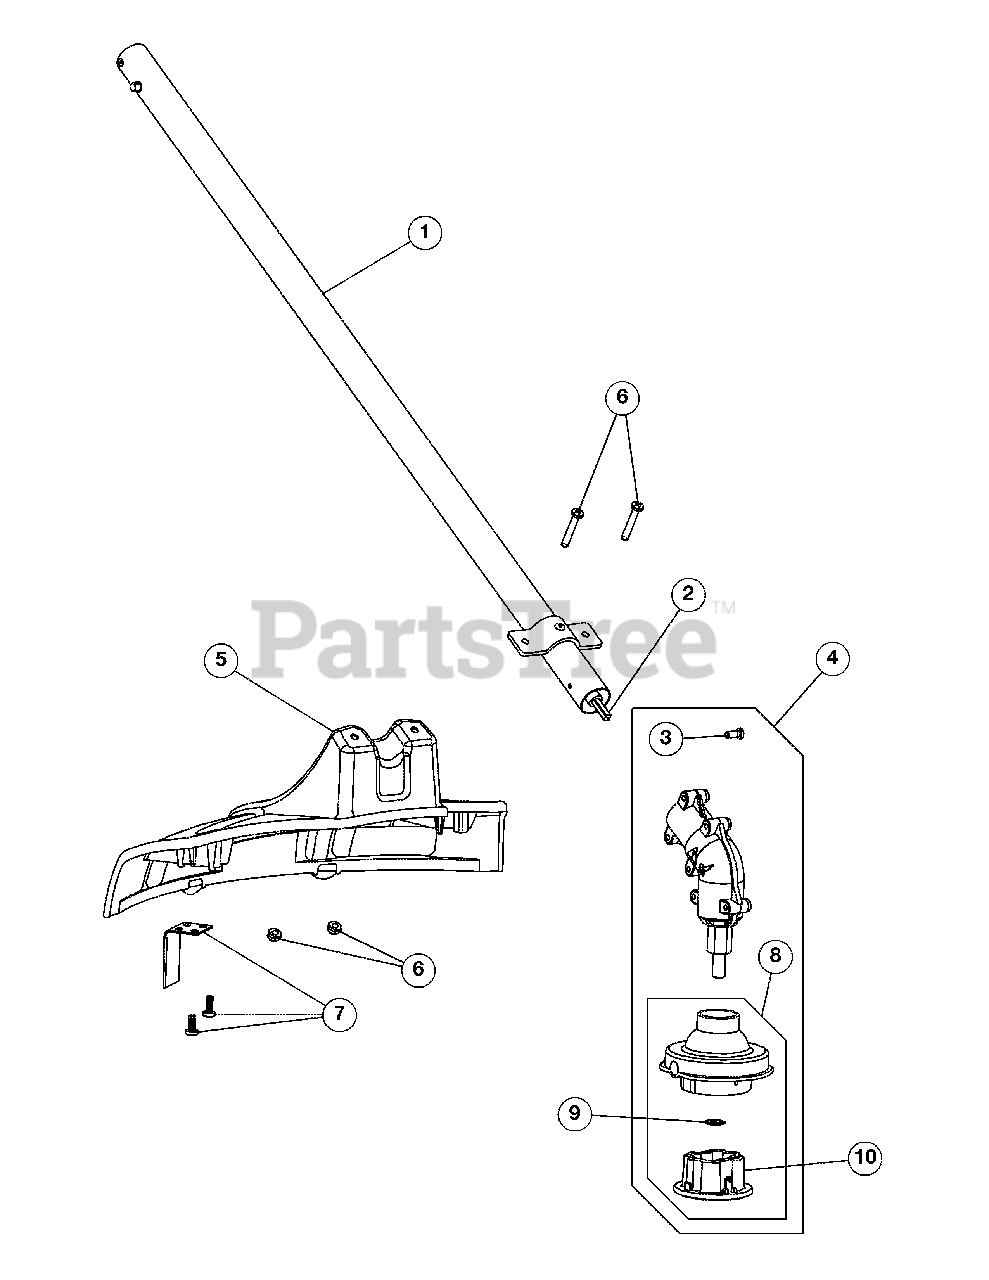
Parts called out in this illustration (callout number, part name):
1	Lower Drive Shaft Housing Assembly
2	Lower Flexible Drive Shaft
3	Anti-Rotation Screw
4	Gear Box Assembly (Incl. 3 & 8)
5	Shield Assembly (Incl. 6 & 7)
6	Shield Mounting Screws
7	Blade Assembly
8	Cutting Head Assembly (Incl. 9 & 10)
9	Retainer
10	Cutting Head Cap
